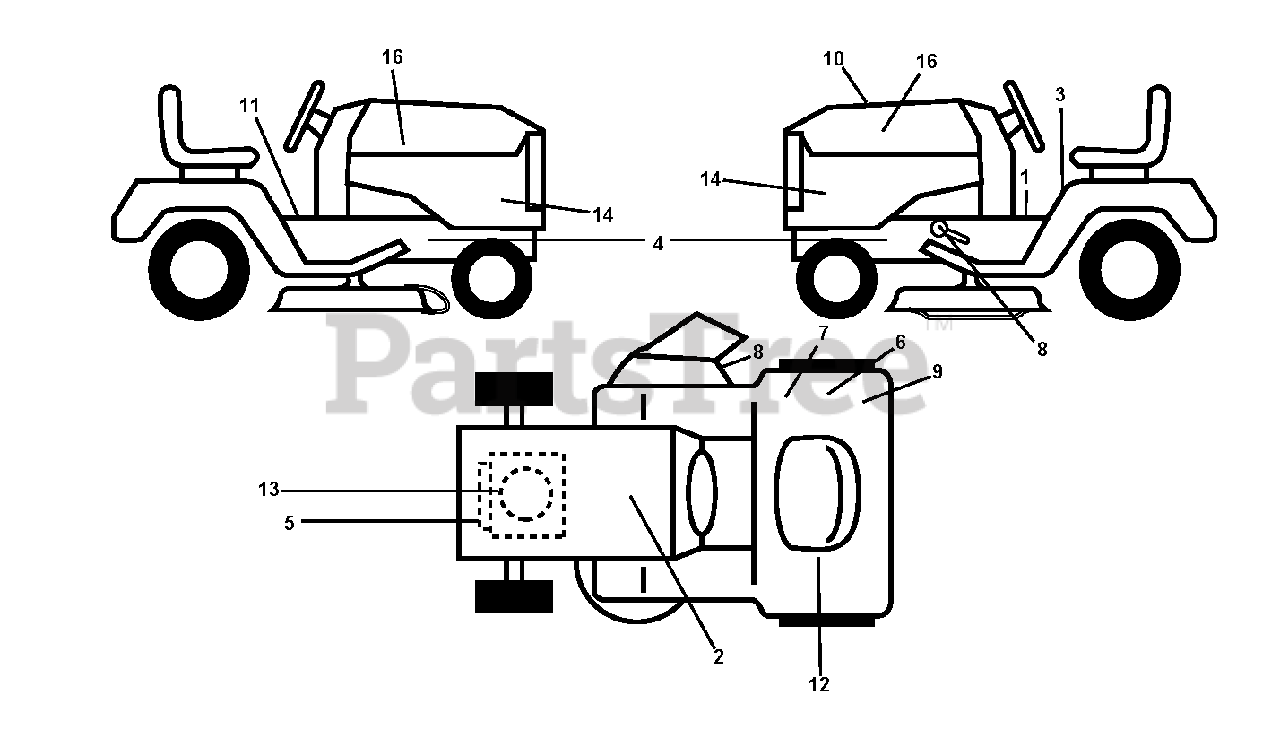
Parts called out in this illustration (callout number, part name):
1	DECAL PARK BRAKE
2	DECAL BTRY SYMBOLS
3	LABEL
5	DECAL, ENG. HP
6	DECAL
7	DECAL 80 DBA
8	DECAL.PEDAL.HUSQ.CROWN
9	DECAL
11	DECAL
12	DECAL.WARN.RESERVE.FUEL
13	DECAL
16	RP.DECAL.BADGE.170MM.TEXTLOGO
